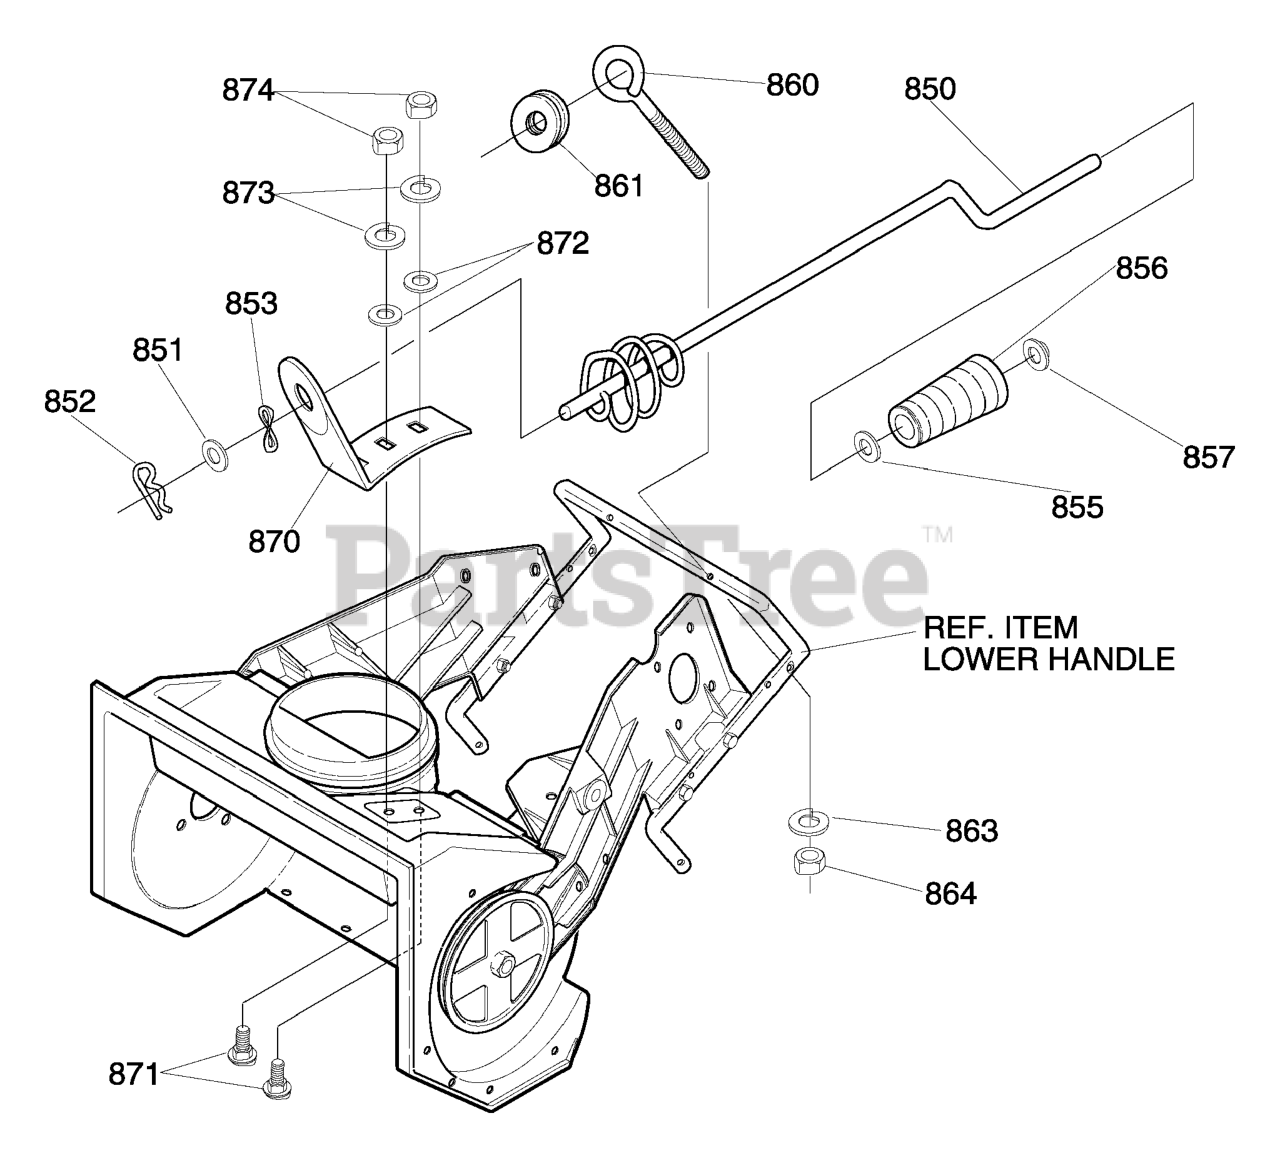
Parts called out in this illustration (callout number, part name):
850	ROD, ASSY UPPER CHUTE
851	FLATWASHER
852	COTTER PIN
853	WASHER, CURVED SPRING
855	FLATWASHER
856	KNOB, SLEEVE
857	NUT, PUSH
860	EYE BOLT 3/8-16x2.00
861	GROMMET, EYE BOLT
863	WASHER, SPLITLOCK
864	NUT, 3/8-16
870	BRACKET, CHUTE ROTATE
871	BOLT, 5/16-18 x .75
872	FLATWASHER
873	WASHER, SPTLOCK
874	NUT, 5/16-18
